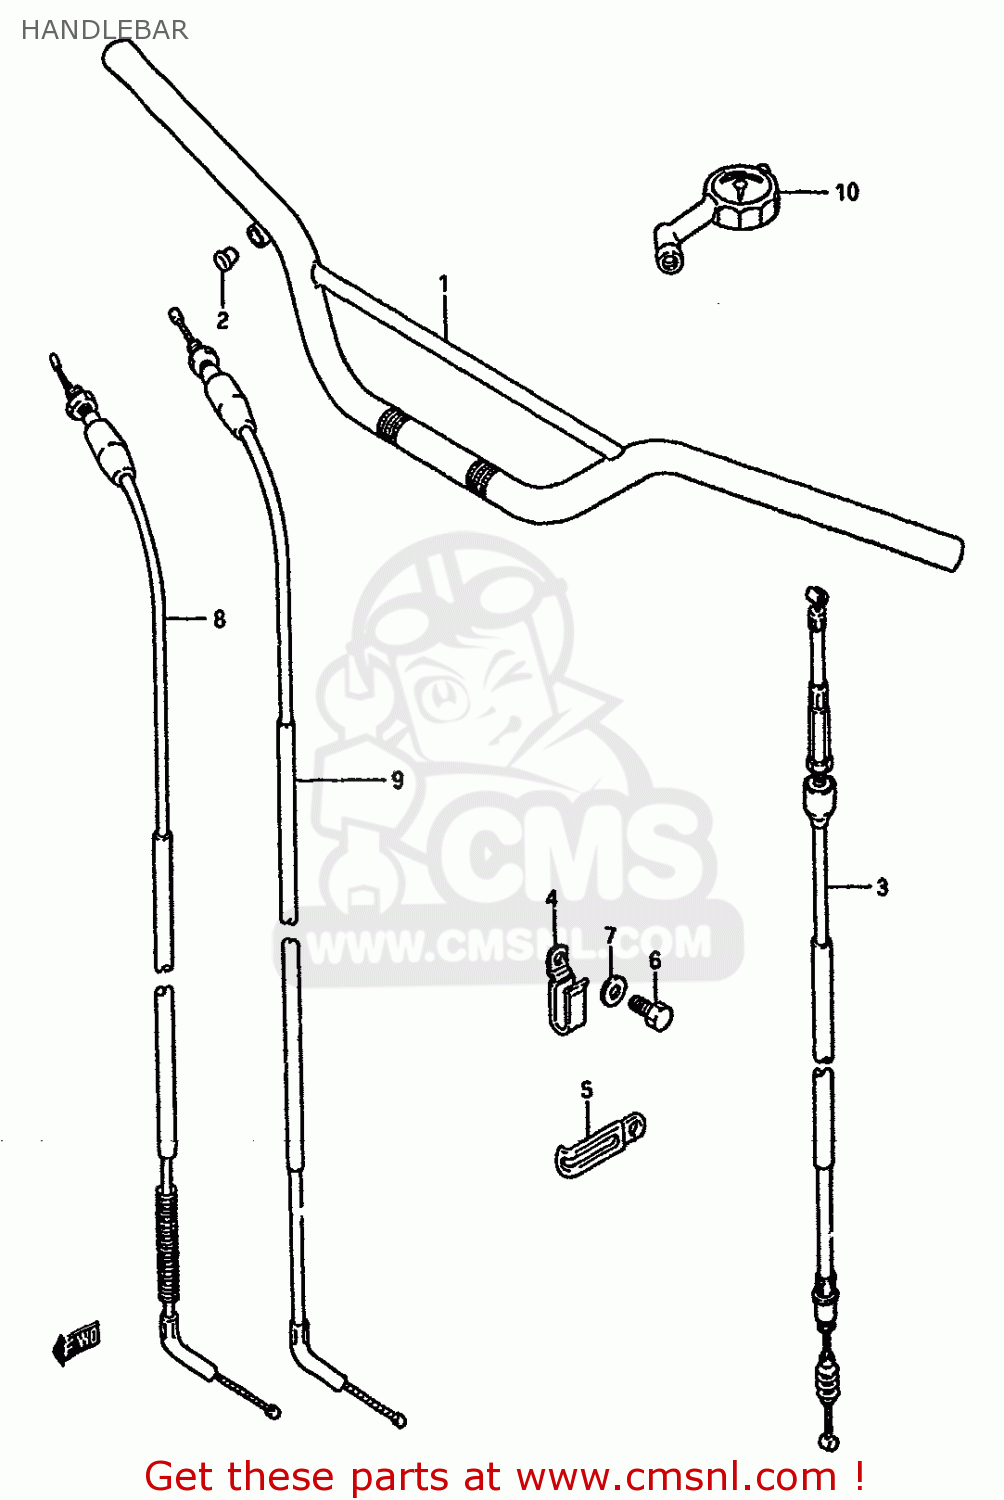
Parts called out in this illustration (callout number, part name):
1	HANDLEBAR
2	CAP(OD:14)
3	CABLE ASSEMBLY,CLUTCH
4	CLAMP
5	CLAMP
6	BOLT
7	WASHER
8	CABLE ASSEMBLY,THROTTLE
9	CABLE ASSEMBLY,THROTTLE
10	GAUGE ASSY,AIR PRESSURE
